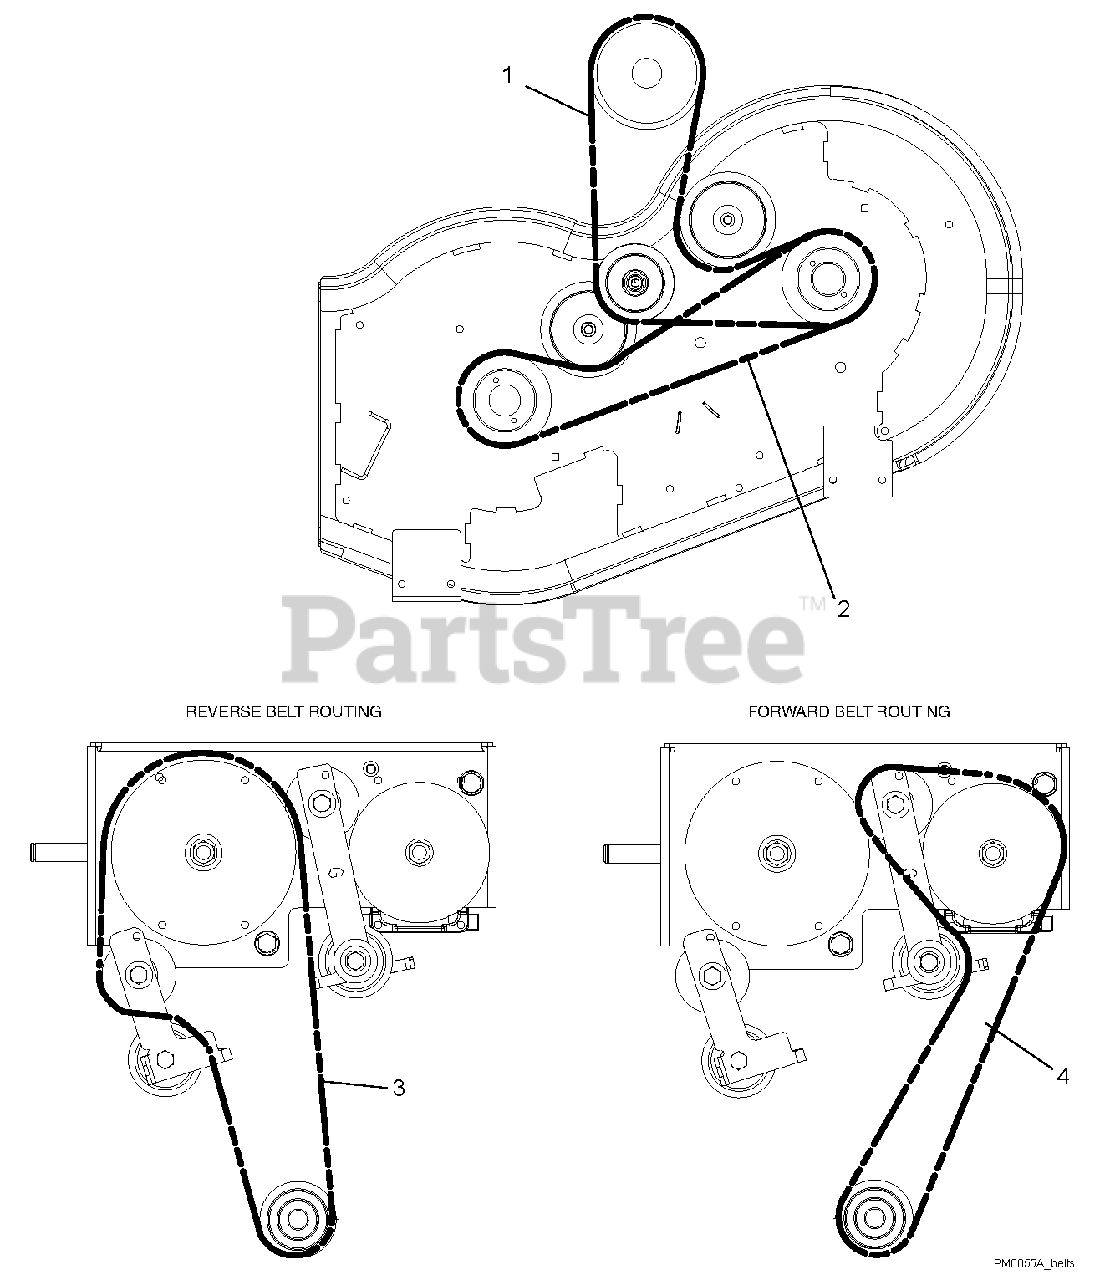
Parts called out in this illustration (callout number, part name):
1	Belt, HA 56.95 Wrapped
2	Belt, HA 51.20 Wrapped
3	Belt, 3L Clutching Cover
4	Belt, 3L Clutching Cover
